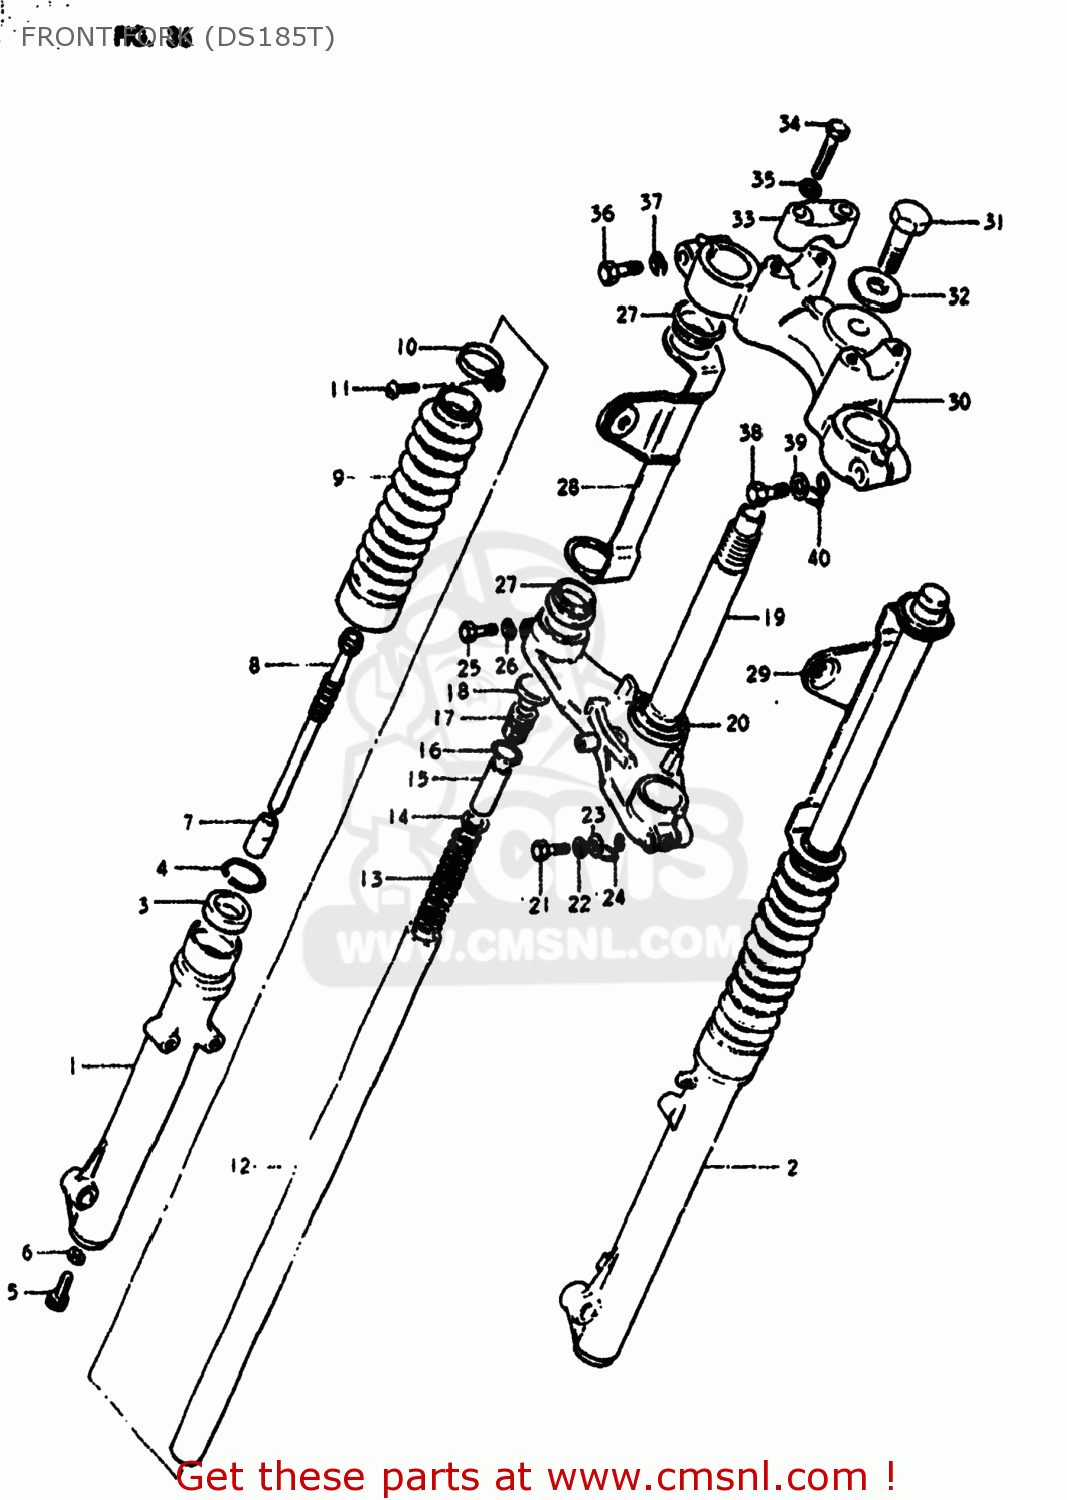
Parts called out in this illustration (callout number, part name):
1	TUBE,FORK,OUTER,RIGHT
2	TUBE,OUTER,LEFT
3	SEAL,OIL
4	RING,STOPPER
5	BOLT,FORK CYLINDER(10X25)
6	GASKET (NAS)
7	PIECE,OIL LOCK
8	CYLINDER,FRONT FORK
9	BOOT (BLACK)
10	BAND
11	SCREW
12	TUBE,INNER
13	SPRING
14	GUIDE,SPRING COVER
15	SPACER,SPRING
16	O-RING,FORK INNER TUBE
17	CAP
18	CAP,FRONT FORK
19	STEM,STEERING
20	RACE,STEERING OUTER LWR
21	BOLT
22	WASHER,LOCK 12
23	WASHER
24	CLIP
25	BOLT
26	WASHER,LOCK 12
27	CUSHION,HEADLAMP BRACKET
28	BRACKET,HEADLAMP HOUSING
29	BRACKET,HEADLAMP,LEFT
30	HEAD,STEERING STEM
31	BOLT,FORK INNER TUBE
32	WASHER,STEM HEAD(10.5X30X3.2)
33	HOLDER,HANDLE(BLACK)
34	BOLT
35	LOCK WASHER
36	BOLT 10X40
37	LOCK WASHER
38	BOLT 10X40
39	WASHER
40	CLIP
